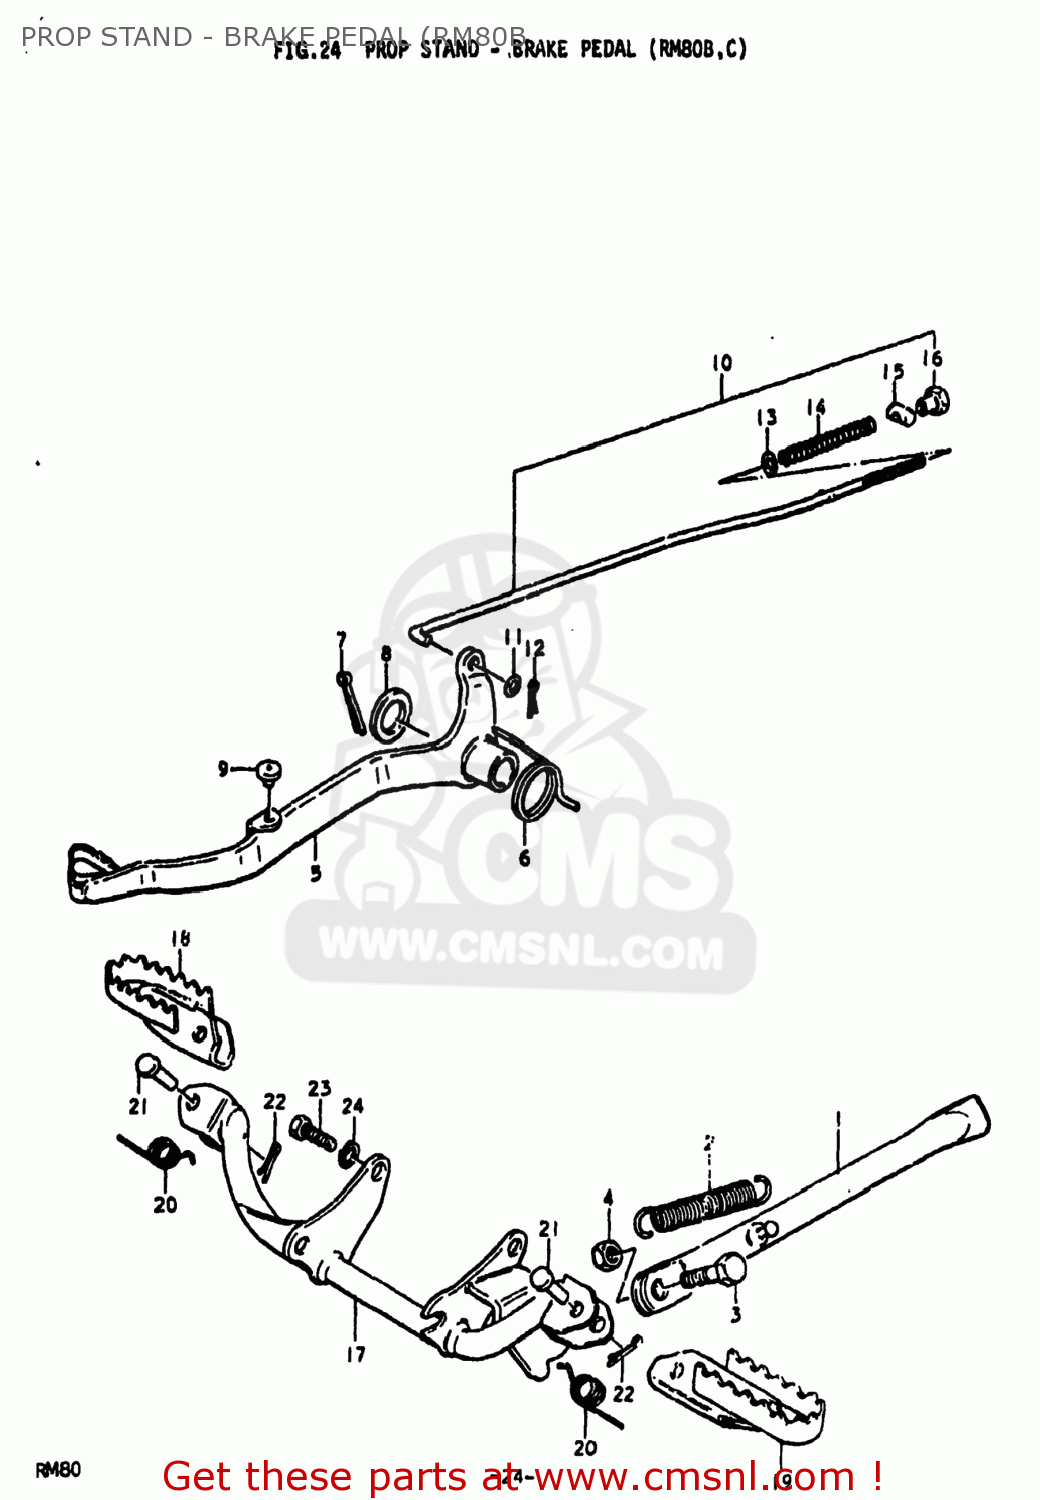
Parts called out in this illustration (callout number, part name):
1	STAND,SIDE
2	SPRING
3	BOLT
4	NUT
5	PEDAL,BRAKE
6	SPRING
7	COTTER PIN
8	WASHER(15.5X26X2.3)
9	STOPPER,BRAKE PEDAL
10	ROD ASSEMBLY,REAR BRAKE
11	WASHER
12	PIN 20X20
13	WASHER
14	SPRING
15	PIN(11X18)
16	NUT
17	BAR,FRONT FOOTREST
18	FOOTREST,FRONT,RIGHT
19	FOOTREST
20	SPRING
21	PIN
22	PIN 20X20
23	BOLT
24	LOCK WASHER
